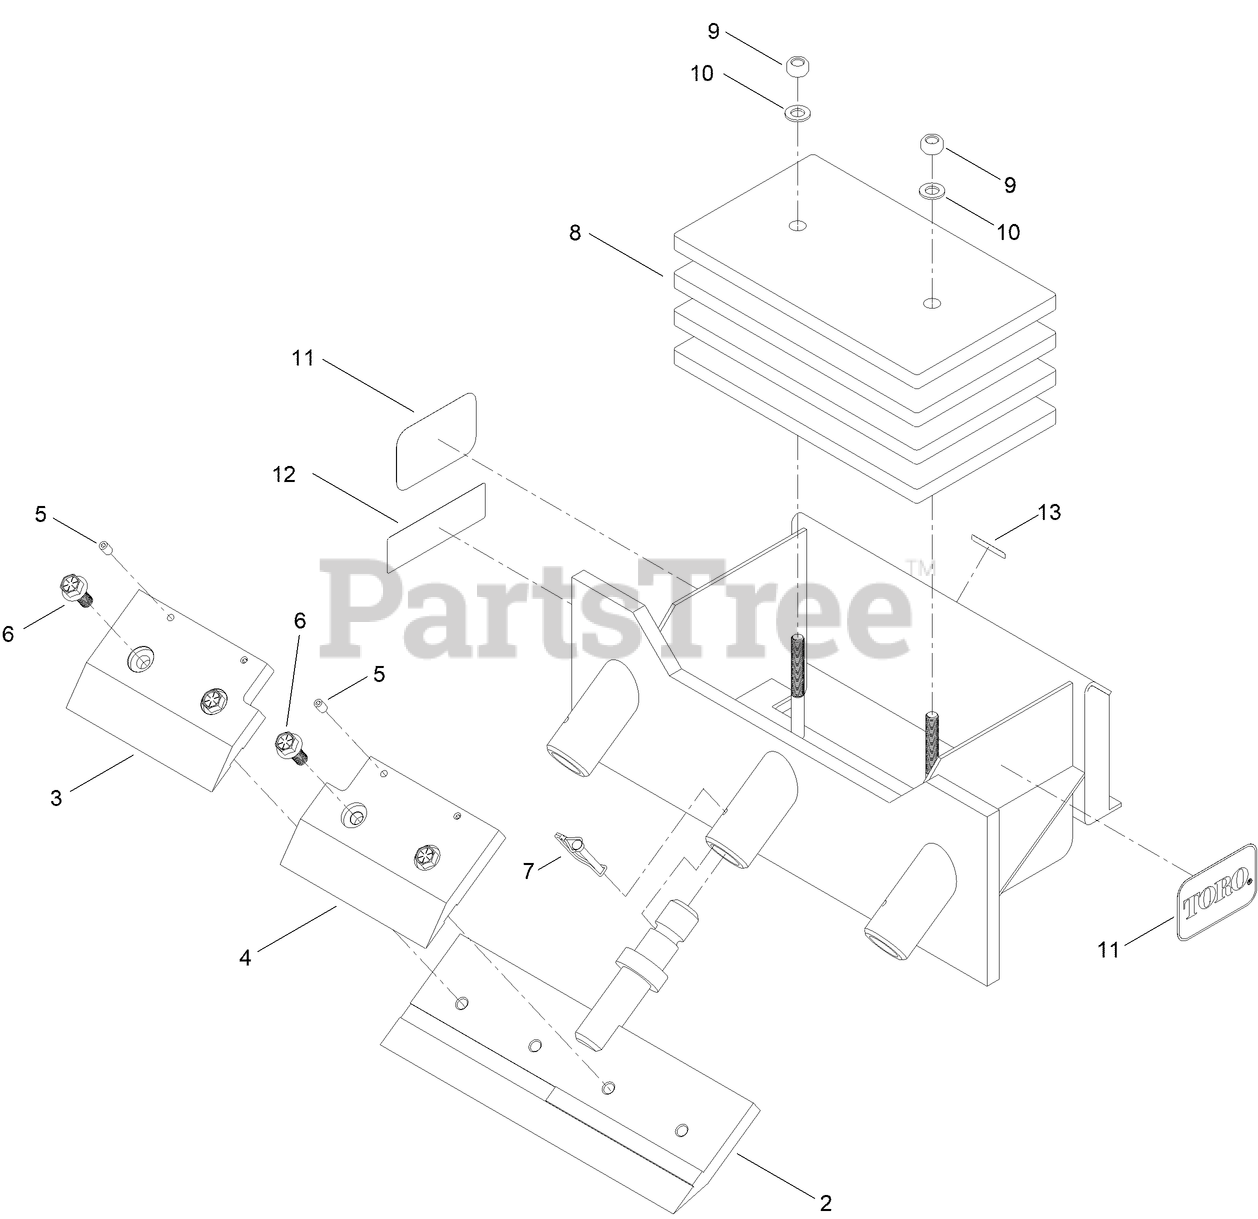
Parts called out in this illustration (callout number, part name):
2	BASE-HOLDER, BLADE
3	CLAMP-HOLDER, 24" BLADE
4	CLAMP-HOLDER, 24" BLADE
5	SCREW-SET, HSH
6	BOLT-BLADE HOLDER
7	PIN-RETENTION
8	WEIGHT
9	NUT-HEX
10	WASHER-FLAT
12	DECAL-SAFETY, SCRAPER
13	DECAL-WARNING
